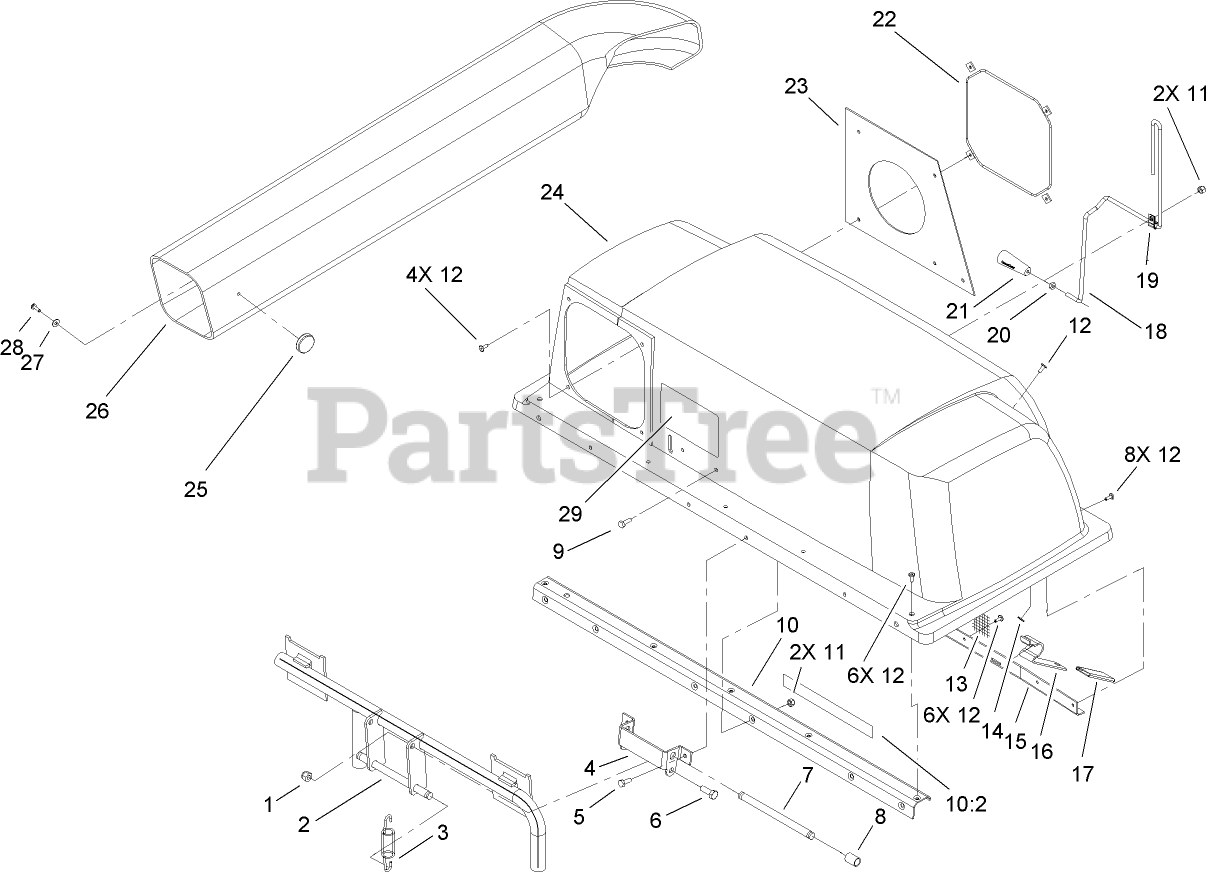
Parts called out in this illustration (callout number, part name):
1	NUT-LOCK, NI
2	FRAME ASM
3	SPRING-EXTENSION
4	HINGE-BAG, TOP
5	SCREW-HH
6	SCREW-HH
7	PIN-SPRING
8	SPACER
9	SCREW-HH
10	STIFFENER ASM
10:2	DECAL-CAUTION
11	NUT-LOCK, NI
12	RIVET-BLIND
13	SCREEN-BAGGER
14	WASHER-FLAT
15	SUPPORT-SCREEN
16	LATCH-BAGGER, TOP
18	FEELER-FILL, BAG
19	CLAMP
20	NUT-JAM
21	HANDLE-TAPERED
22	CLAMP-SEAL
23	SEAL-CHUTE
24	TOP-BAGGER
26	CHUTE-DISCHARGE
27	WASHER-PLAIN
28	SCREW-PPHTF
29	DECAL
